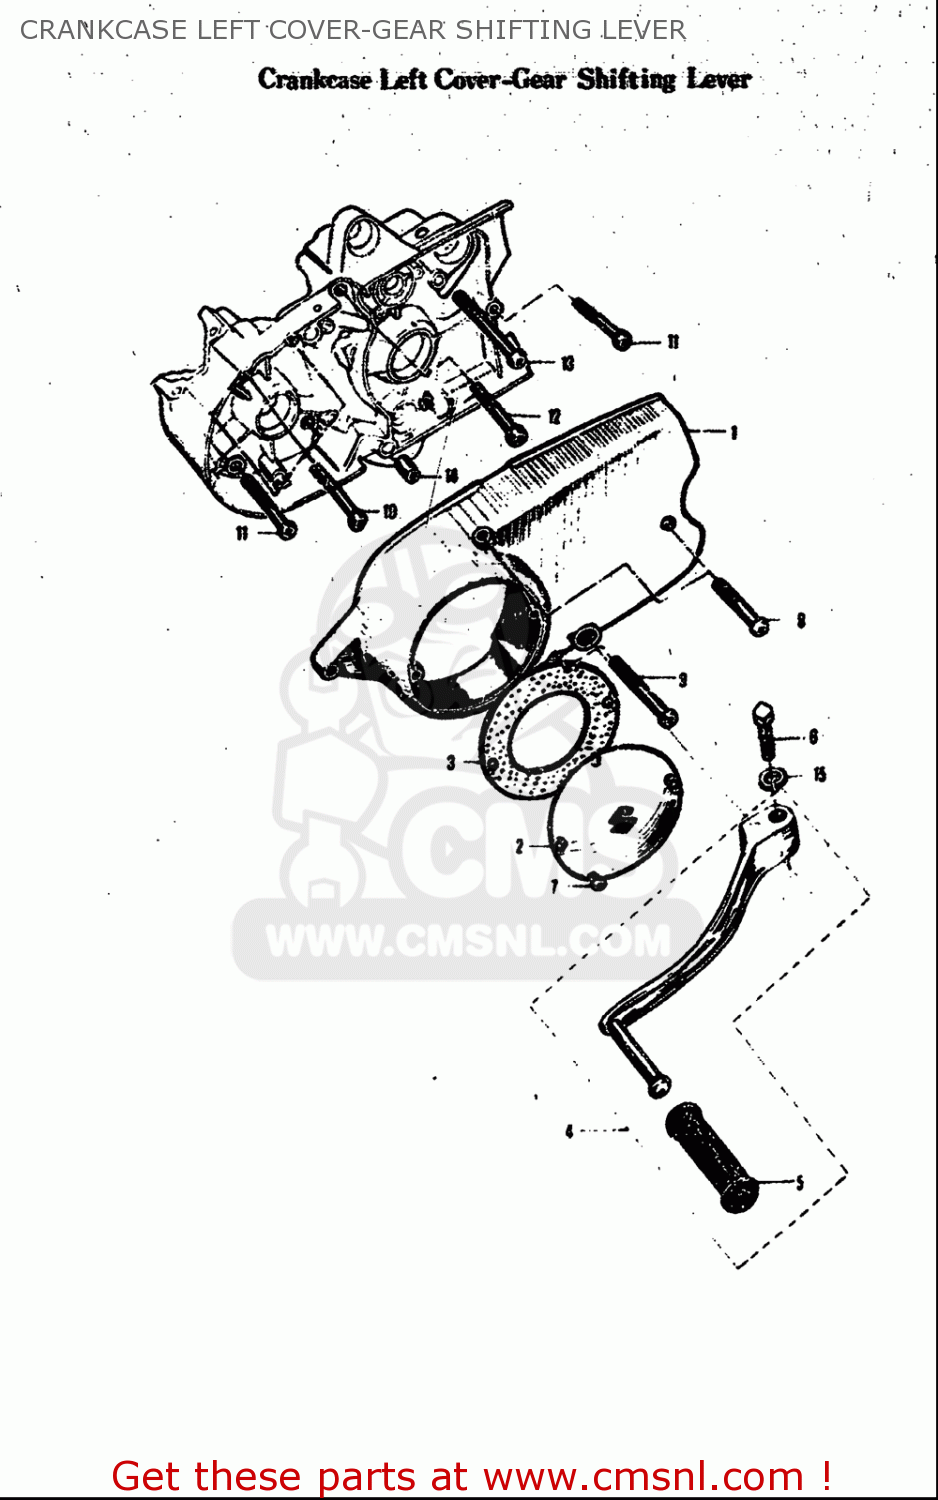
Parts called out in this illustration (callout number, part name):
3	GASKET,OIL PAN (MCA)
5	RUBBER,GEAR SHIFT PEDAL
6	BOLT
10	SCREW
11	SCREW
12	SCREW
13	SCREW
14	PIN
